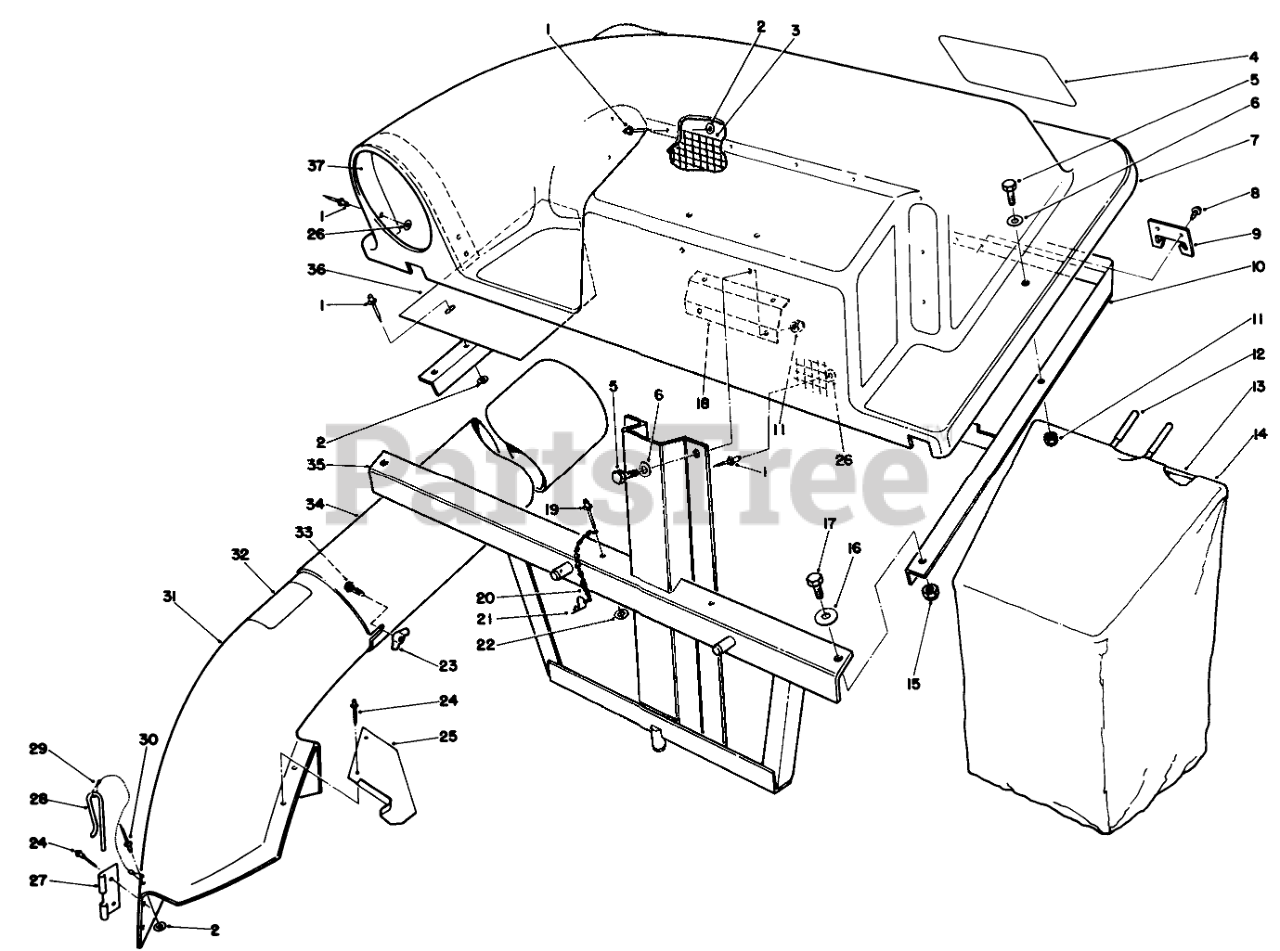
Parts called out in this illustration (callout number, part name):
1	Rivet-Pop
2	Washer
3	SCREEN
4	DECAL-BAGGER, TWIN
5	SCREW-HH
6	WASHER-PLAIN
7	COVER-BAGGER, TWIN
8	Bolt 1/4-20
9	BRACKET-FRAME, BAG
10	Cover-Frame
11	NUT-LOCK, NI
12	GRIP-HANDLE, BAG
13	Frame-Bag
15	NUT-LOCK, NI
16	WASHER-FLAT
17	SCREW-HH
18	Plate-Backup
20	10 LINK CHAIN W/O HOOK
21	PIN-HAIR
22	WASHER-BACK
23	NUT-WING SPECL
24	RIVET-BLIND
25	CHUTE SUPT BRKT
26	WASHER-FLAT
27	BRACKET-MOUNTING, CHUTE
28	PIN-LOCKING, CHUTE
29	LANYARD
30	RIVET-BLIND
31	Chute Assembly (Incl. Ref. #24-30 & 32)
32	DECAL-DANGER
33	BOLT-CARR
34	TUBE(ROUND&LONG)
35	Frame-Mounting
36	Baffle
37	Support Inlet
